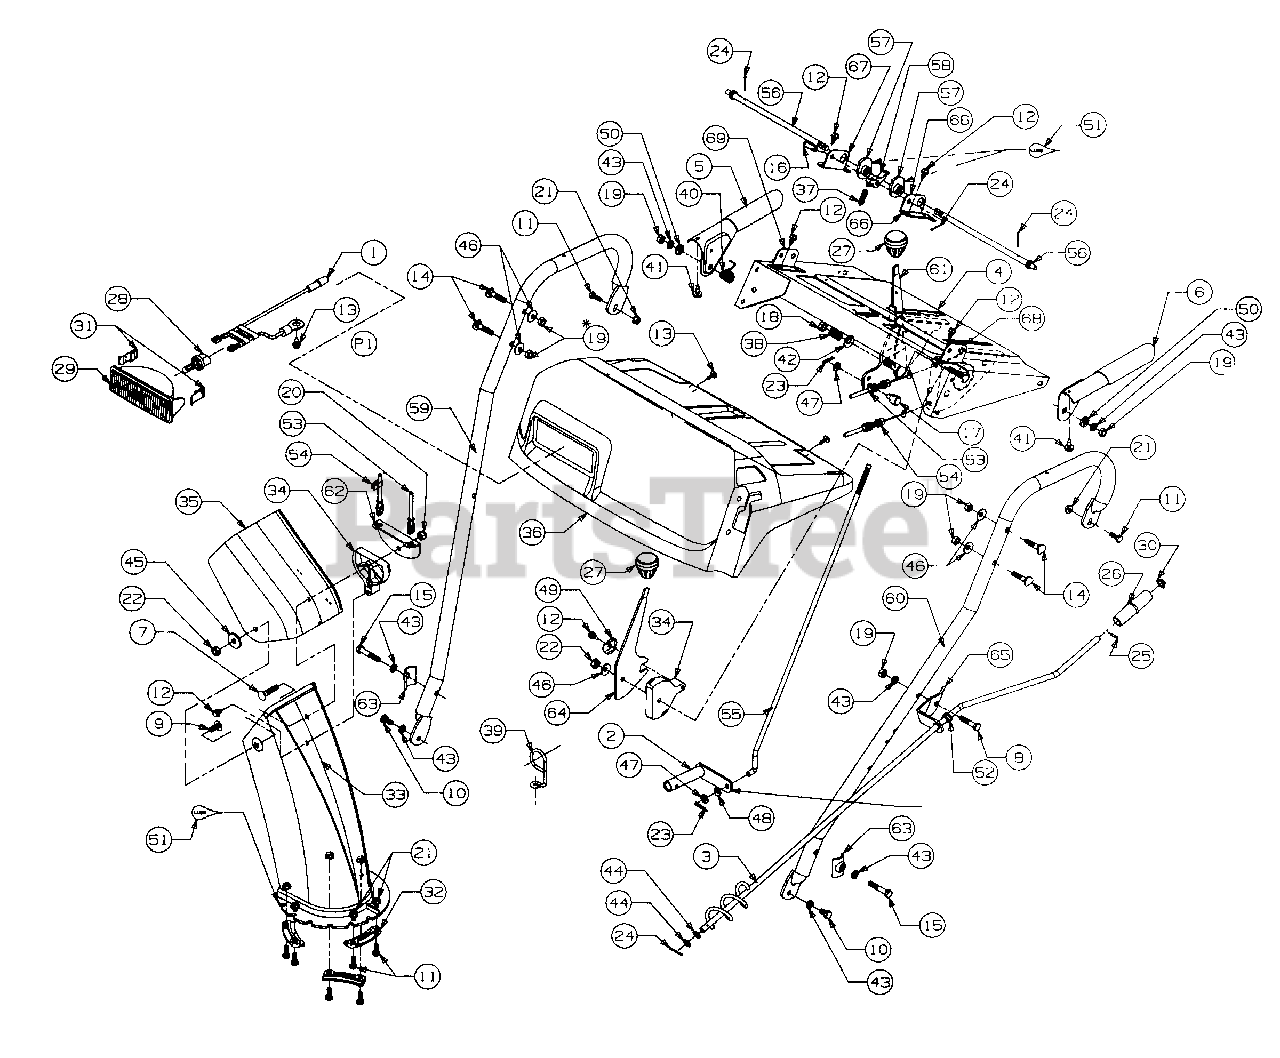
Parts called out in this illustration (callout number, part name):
1	Harness - Light
3	Crank Assembly
6	Handle Assembly L.H.
7	Screw Carriage
8	Screw - Hex Cap
9	Screw - Carriage
10	Screw - Hex Lock
11	Screw - Hex Cap
13	Screw - Self Tap
14	Bolt - Carriage
15	Screw - Hex
16	Pin - Clevis
17	Ferrule
18	Nut - Lock Hex
19	Nut - Hex
20	Nut - Lock Hex
21	Nut - Lock Flanged Hex
22	Nut - Patch Lock Hex
23	Pin - Cotter
24	Pin - Cotter
25	Roll Pin
26	Knob - Chute Crank
27	Knob - Shift
28	Lamp - Halogen
29	Housing - Lamp Lens
30	Cap - Push
31	Clip - Retaining
32	Chute - Flange Keeper
33	Chute - Lower
34	Cable - Guide
35	Chute - Upper
36	Handle Panel (524 & 524T)
37	Spring - Compression
38	Spring - Compression
39	Cable Control Wire
40	Spring - Torsion
42	Washer - Bell
43	Washer - Lock
44	Washer - Flat
46	Washer - Bell
47	Washer - Flat
48	Washer - Spring
49	Washer - Special
50	Washer - Special
51	Lubricant
52	Bushing - Plastic
53	Cable - Chute Deflector
54	Cable - Chute Deflector w/Clip
55	Rod - Shift
56	Rod - Cam
57	Cam Handle Lock
58	Pawl Handle Lock
59	Handle R.H.
63	Handle Tab
